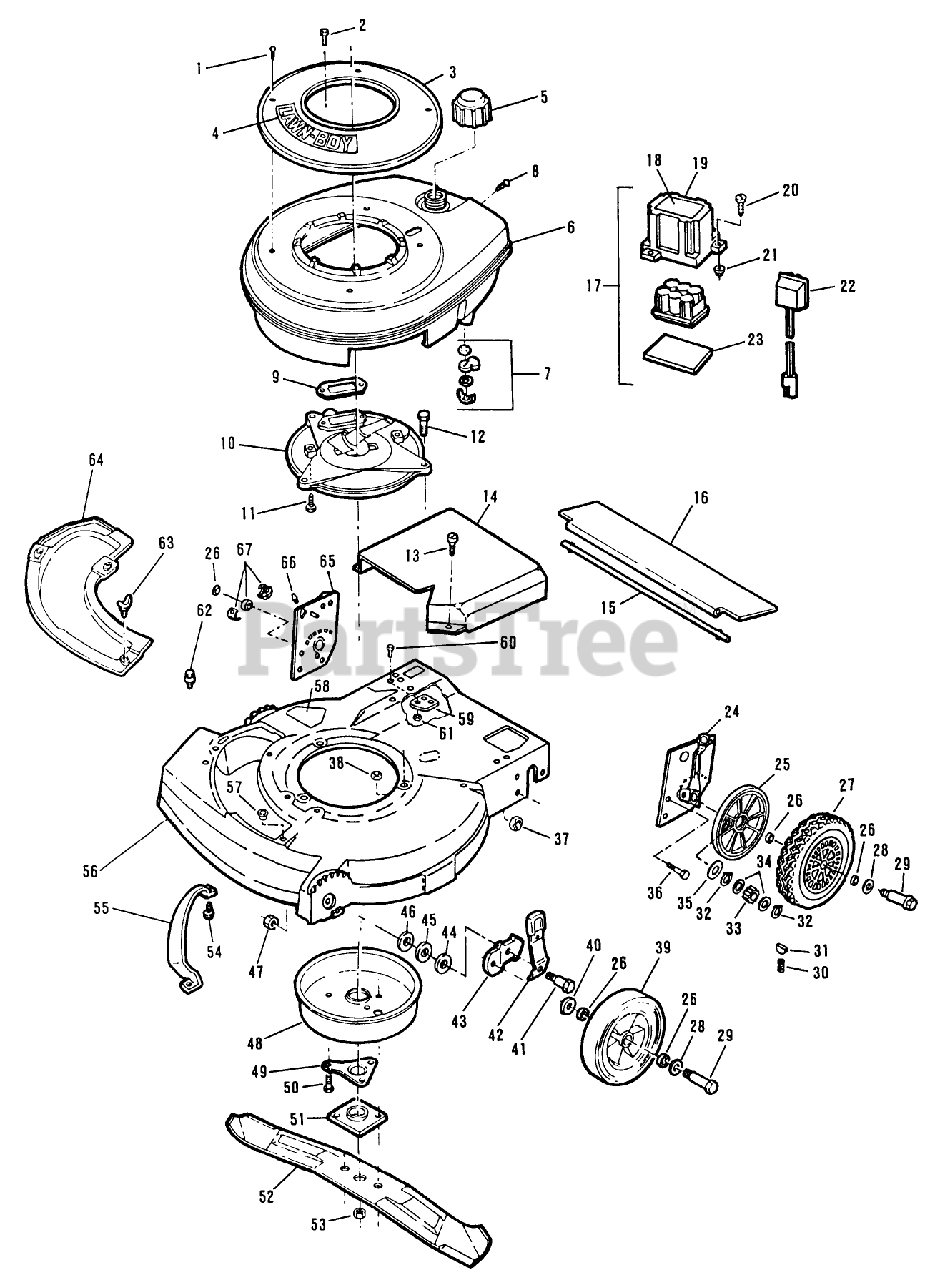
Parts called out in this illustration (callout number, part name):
1	SCREW - SELF TAPPING
2	SCREW SEMS SM
5	FUEL CAP & INSERT
7	SHUT OFF VALVE KIT
8	SCREW S
11	SCREW V
12	SCREW-HH
13	SCREW SEMS TRM HEX HD
20	SCREW - SELF TAPPING
21	NUT-CLIP
23	PAD-BATTERY
26	WASHER
28	SPACER
29	BOLT WHEEL
30	SPRING
31	KEY
32	RET RING
33	PINION BROCKWAY
34	SPACER/GR ALGHNY
37	NUT-LOCK F
38	NUT-LOCK F
40	WASHER WROUGHT
41	BOLT
42	SPRING ARM ASM
44	WASHER
45	WASHER
46	WASHER
47	LOCKNUT
48	MUFFLER COVER F
49	SUPPORT F
50	SCREW
51	PLATE AND COLLAR ASM
53	NUT-BLADE
55	BAR-TOE
59	BOLSTER
61	LOCKNUT E
63	WING SCREW LAWRE
66	**FITTING LINCOLN
67	REAR AXLE BEARING
